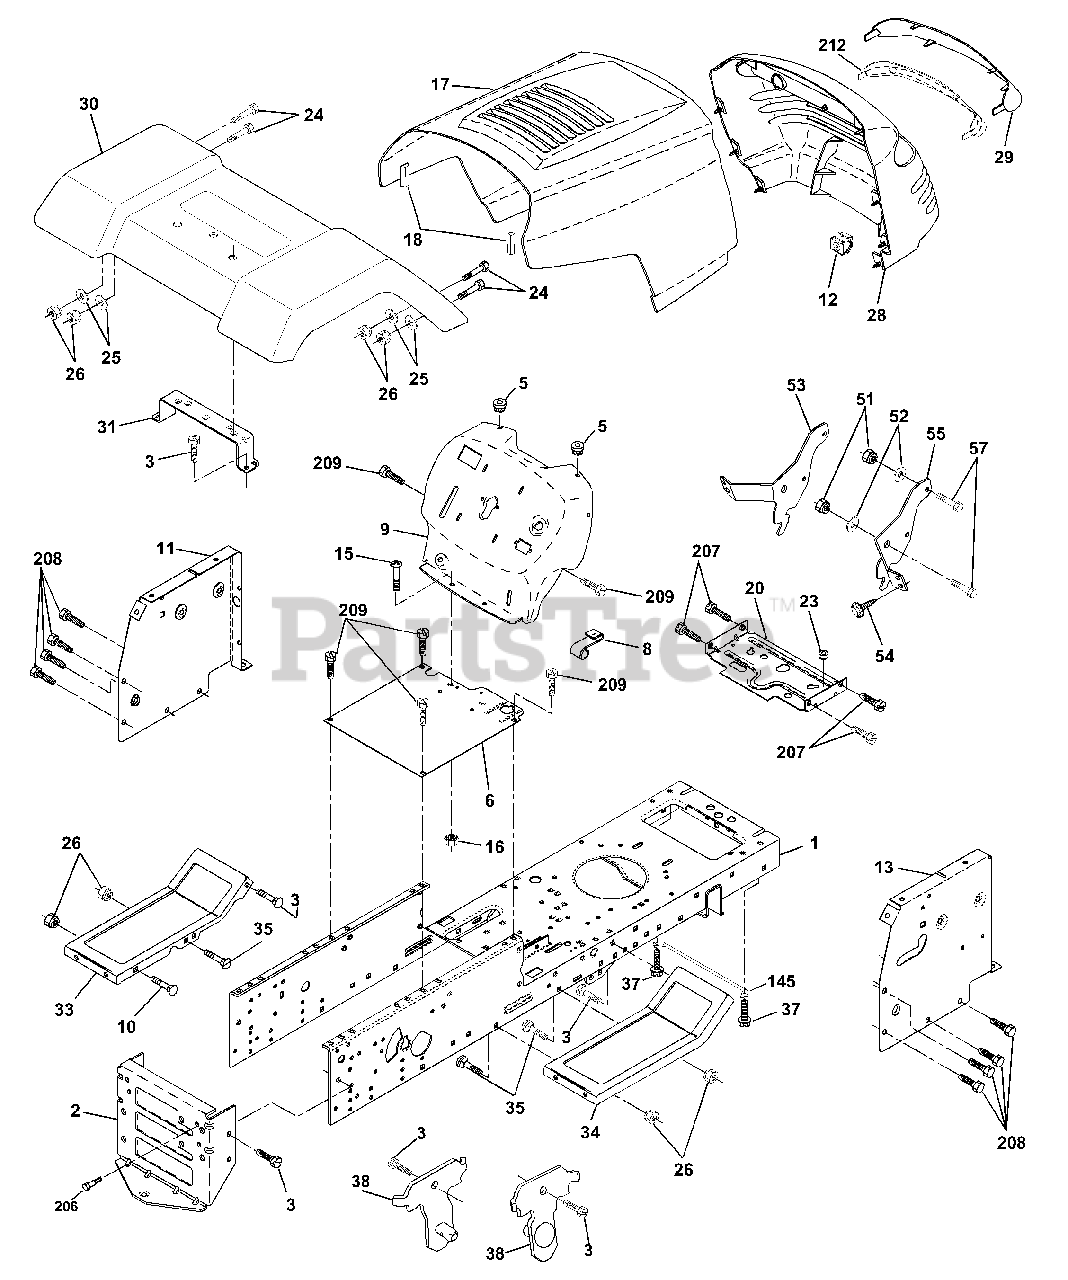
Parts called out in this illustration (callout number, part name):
2	Drawbar
3	Screw 3/8-16 x 3/4
5	Bumper Hood/Dash
6	Saddle Flat Lt Fender Shift
8	Clip Retainer Slide-On
9	Dash
10	Bolt Rd Hd Sqnk. 3/8-16 Unc x 1
11	Panel Asm. Dash Lh
12	Clip Tinnerman Grile P/L
15	Screw Mach Trhd 5/16-18 Unc x 3/4
16	Nut Keps 5/16-18 Unc
17	Hood
18	Bumper Hood
20	Plate Mtg Battery/Fuel Tank Fr
23	Bushing Snap Nyl Blk Fuel Line
24	Bolt Fin Hex 3/8-16 Unc x 1 Gr. 5
25	Washer 13/32 x 13/16 x 12 Ga.
26	Nut Lock Hex w/Insert 3/8-16 UNC
28	Grill/Lens Asm
29	Lens Quadra
30	Fender Asm
31	Bracket Fender
33	Footrest Lh
34	Footrest Rh
35	Bolt Rd Hd Sht. Sqnk. 3/8-16 x 3/4
37	Screw Thdrol 5/16-18 x 1/2 Tyt
38	Bracket Asm. Pivot Mower Rear
51	Nut Lock Hex W/Ins. 1/4-20
52	Washer 9/32 x 7/8 x 16 Ga.
53	Bracket Grille LH
54	Screw Hex Wshd 8-18 x 7/8
55	Bracket, Grille RH
57	Bolt Fin Hex 1/4-20 x .75
145	Rod Pivot Chassis/Hood
206	Bolt shoulder 5/16-18
207	Screw Thdrol 5/16-18 x 1/2
208	Screw Thdrol 3/8-16 x 1/2
209	Screw Hex Wsh Thdrol 3/8-16
212	Insert Lens Reflector
